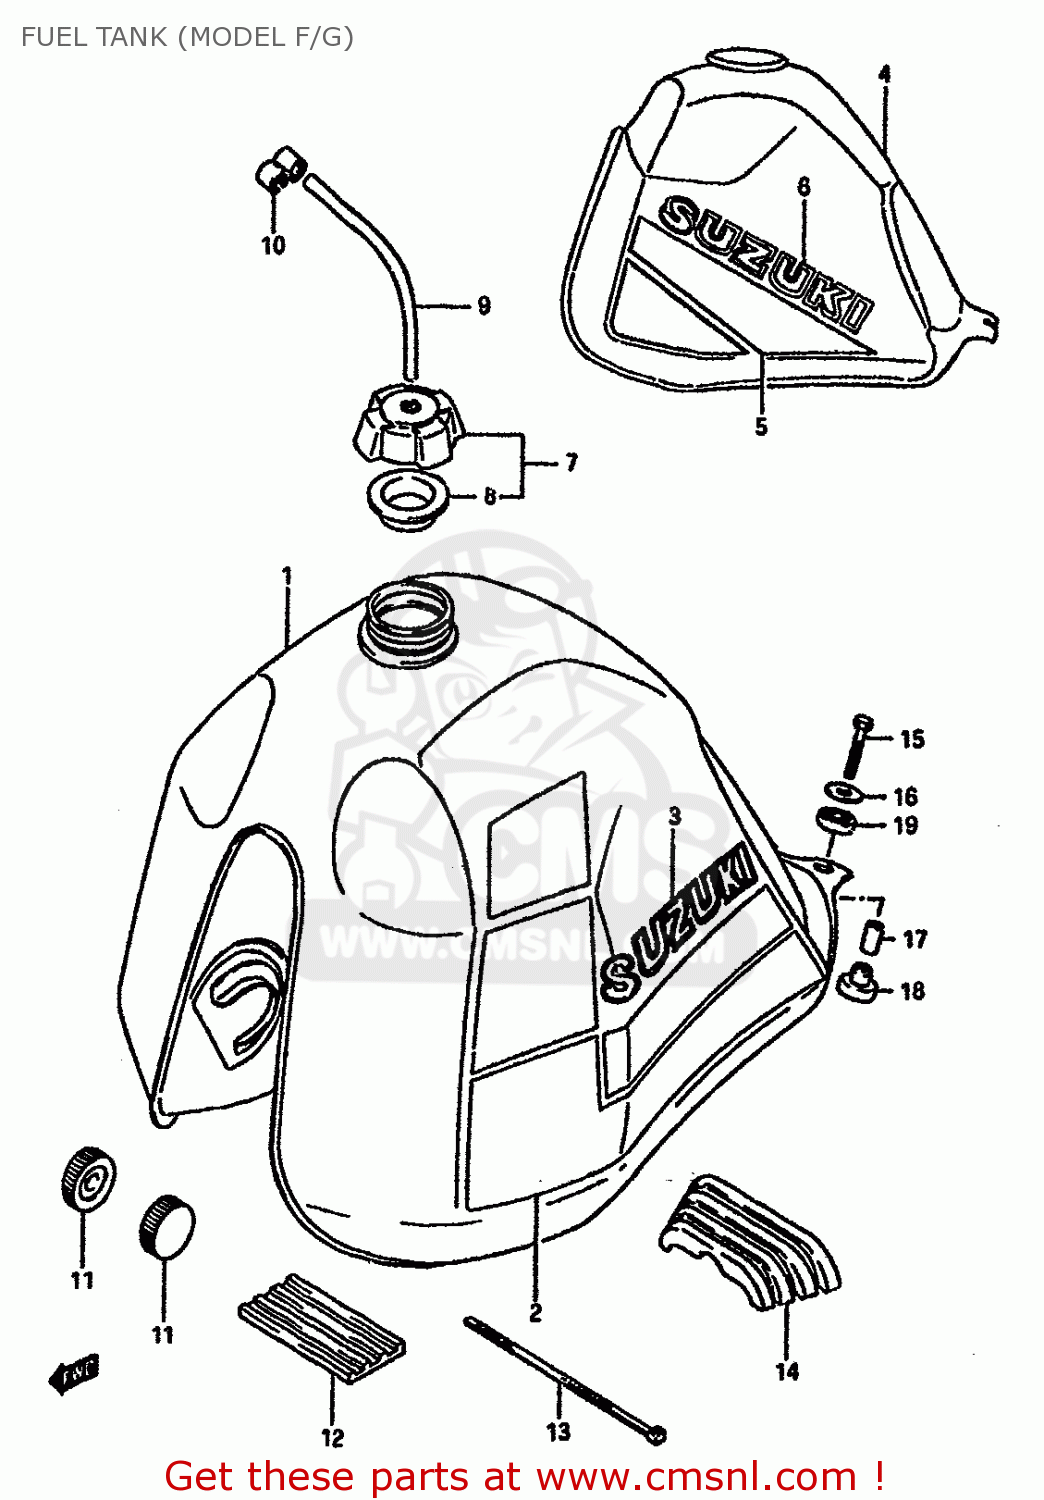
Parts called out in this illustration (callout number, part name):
1	TANK ASSY,FUEL (RED)
2	TAPE SET,FUEL TANK
3	EMBLEM
4	TANK ASSY,FUEL (RED)
5	TAPE SET,FUEL TANK
6	EMBLEM,FUEL TANK
7	CAP SET,FUEL TANK
8	GASKET,FUEL TANK CAP (NAS)
9	HOSE
10	CLAMP,FUEL TANK BREATHER HOSE
11	CUSHION
12	CUSHION,FUEL TANK UPR FR
13	CLAMP
14	CUSHION,FUEL TANK RR
15	BOLT
16	WASHER (6.5X24X1.6)
17	SPACER
18	CUSHION
19	CUSHION
